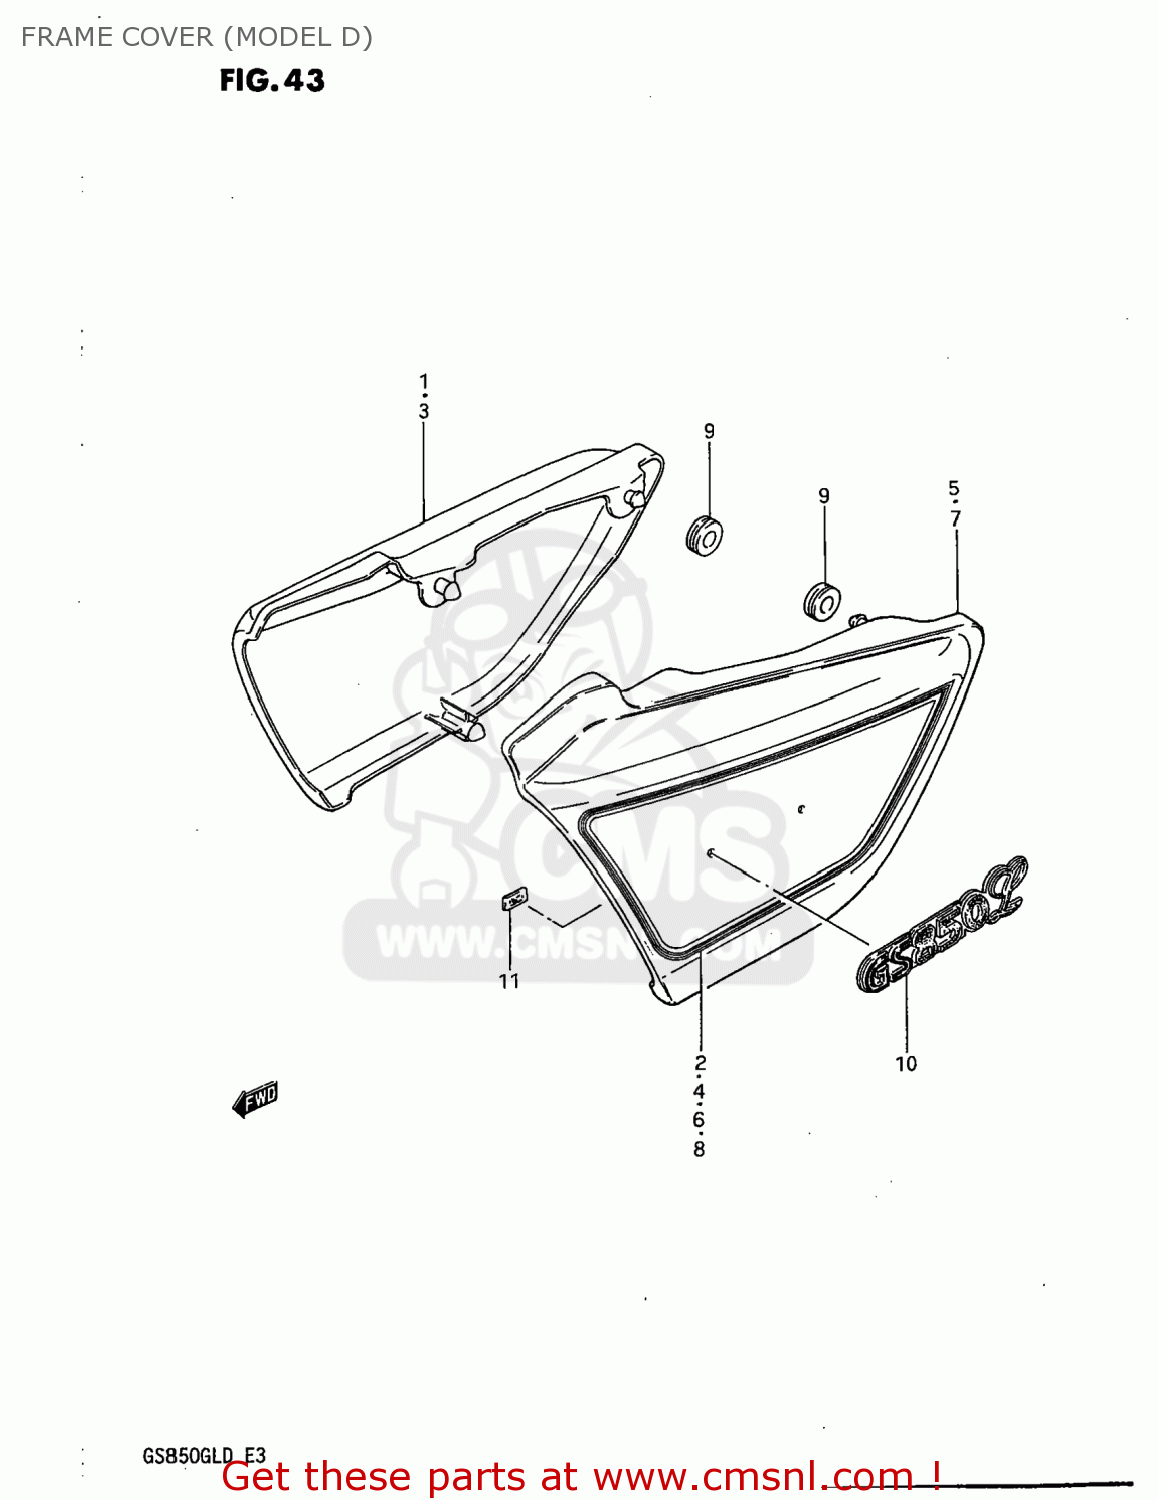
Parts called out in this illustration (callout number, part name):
1	COVER,FRAME,RIGHT
2	TAPE SET,FRAME COVER
3	COVER,FRAME,RIGHT
4	TAPE SET,FRAME COVER
5	COVER,FRAME,LEFT
6	TAPE SET,FRAME COVER
7	COVER,FRAME,LEFT
8	TAPE SET,FRAME COVER
9	CUSHION
10	EMBLEM,FRAME COVER
11	NUT
